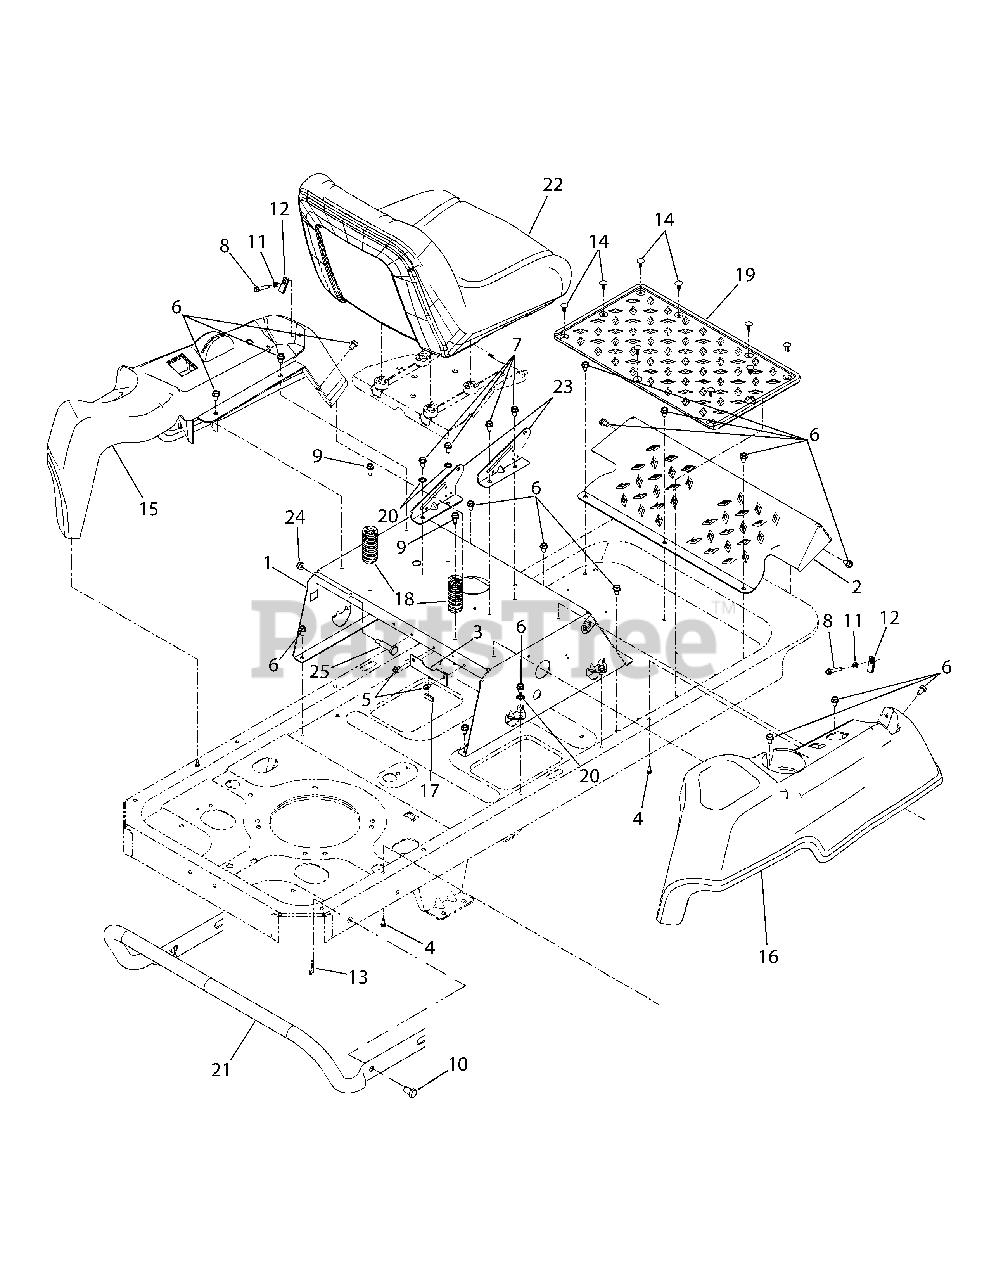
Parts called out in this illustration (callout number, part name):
4	Screw, Hex Wash. Hd Tapp, #12-16 x .50
5	Screw, Hex Wash. Hd. Tapp., 1/4-20 x .5
6	Screw, Hex Wash. Hd. Tapp, 5/16-18 x .625
7	Screw, Hex Wash. Hd. Tapp, 5/16-12 x .75
8	Screw, Hex Wash. Hd. Tapp. , 1/4-20 x 1.5
9	Screw, Hex Wash. Hd Tapp, 5/16-18 x .75
10	Pin, Clevis, .5 x .78
11	Nut, Hex Jam, 1/4-20 GR2
12	Nut, U Type Speed, 1/4-20
13	Pin, Internal Cotter
14	Clip, Ratchet
15	Console, LH
16	Console, RH
17	Strip, Trim
18	Spring, Compression, 1.28 x 3.125
19	Pad, Foot
20	Washer, External Tooth, 3/8
24	Nut, Hex Insert Flange Lock, 1/4-20 GrF
25	Screw, Shoulder, .374 x 1.16
